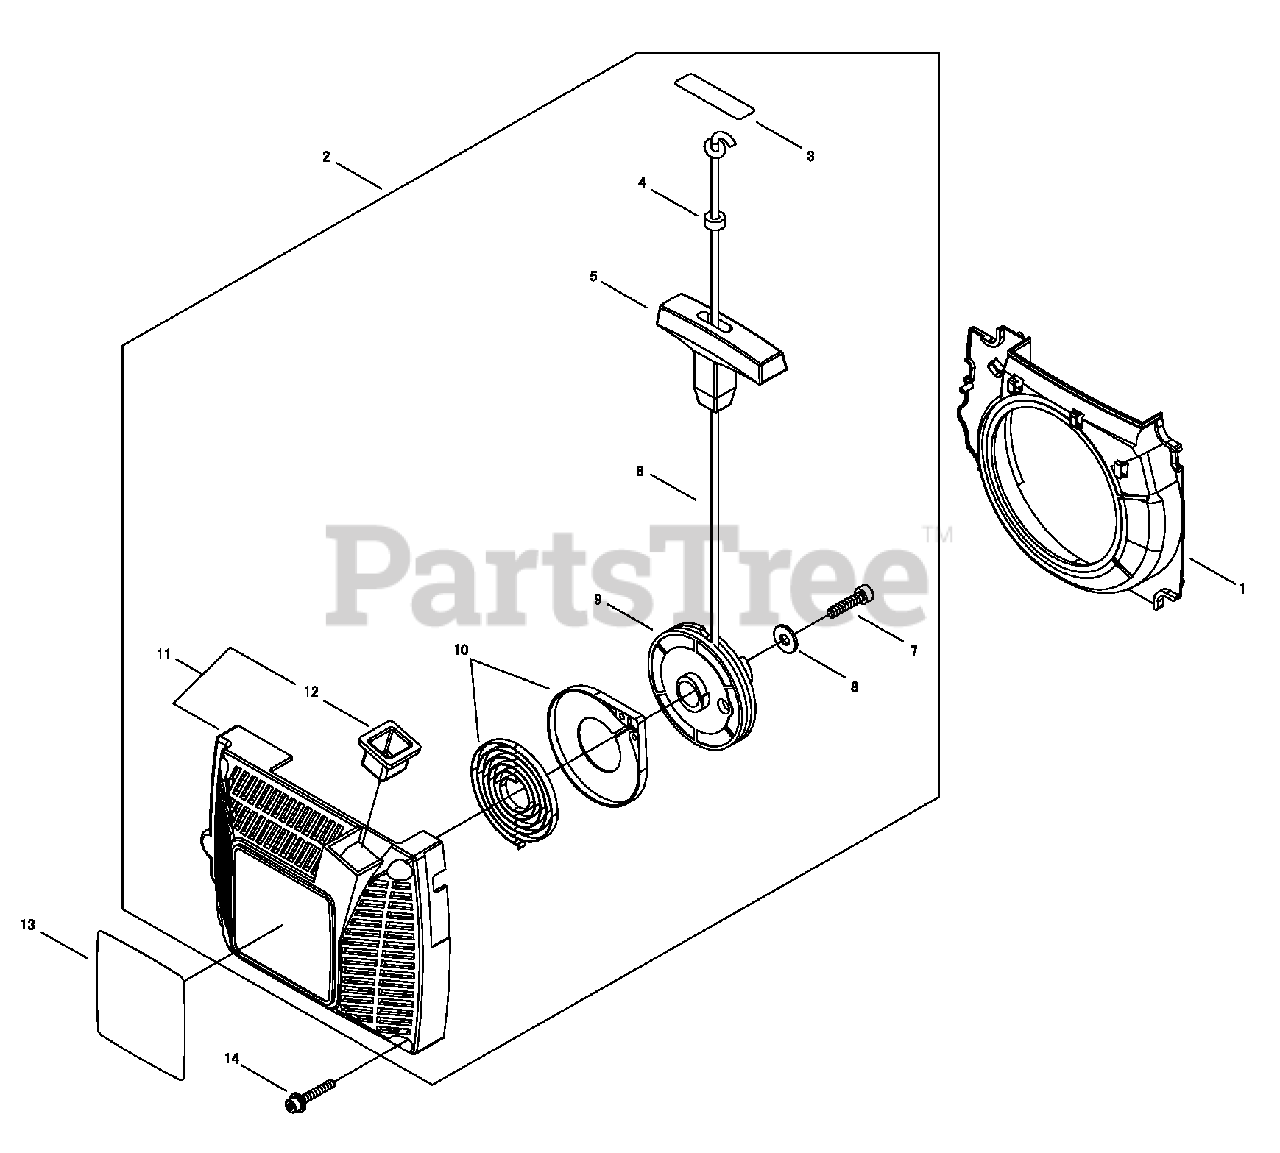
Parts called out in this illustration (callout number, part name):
1	PLATE, AIR
2	STARTER ASSY
3	TAPE, ADHESIVE
4	STOPPER KNOB
5	GRIP, STARTER
6	ROPE, STARTER
7	SCREW - 5X12
8	WASHER
9	REEL, ROPE
10	SPRING, REWIND
11	CASE, STARTER
12	GUIDE, ROPE
13	LABEL - TRADE
14	SCREW - 4X16
